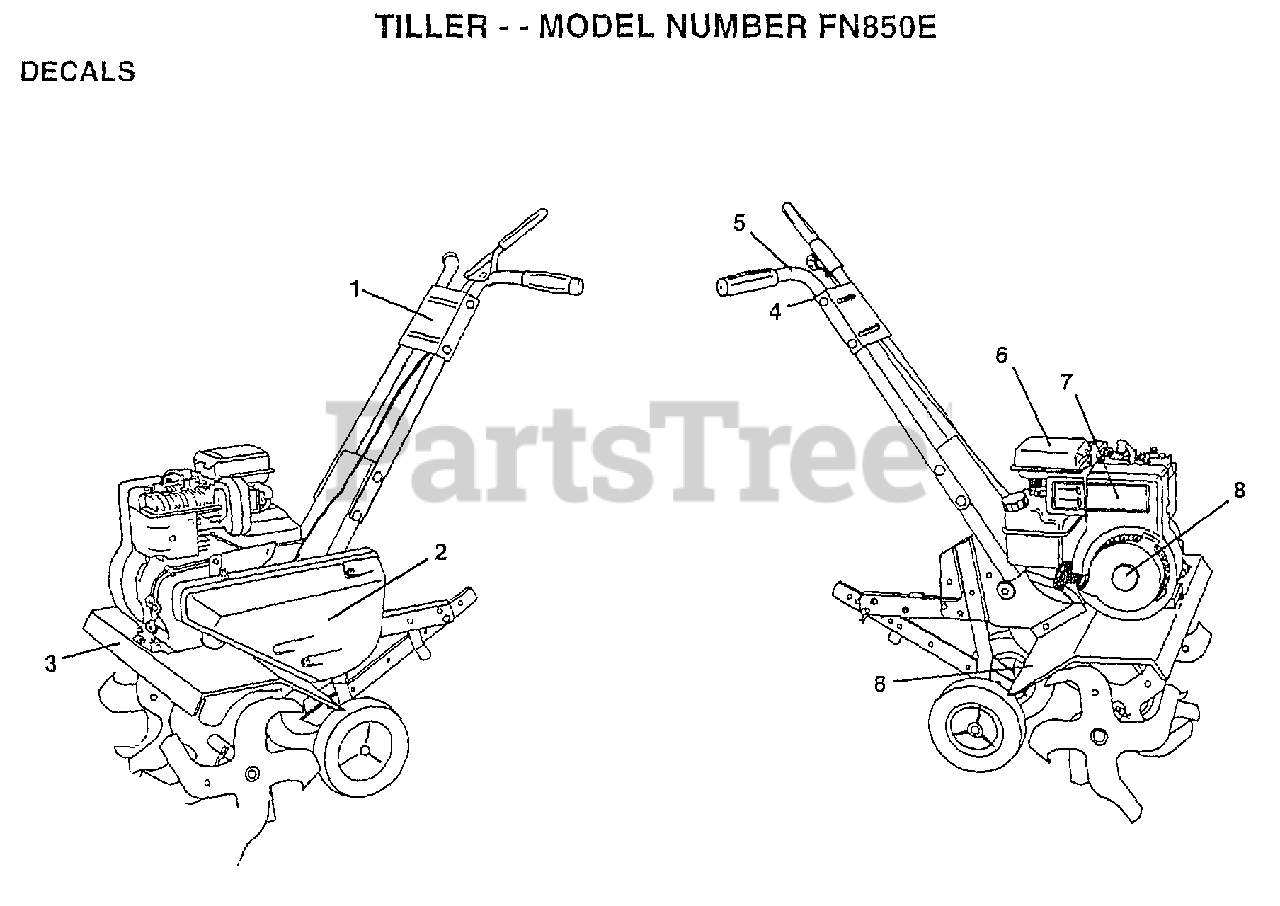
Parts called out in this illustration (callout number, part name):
1	DECAL HANDLE BRKT
2	BELT.GUARD.DECAL
3	DECAL TINE SHIELD
4	DECAL TI
5	DECAL TI
6	DECAL TI
7	DECAL, BRIGGS & STRATTON
9	DECAL, 5 HP
